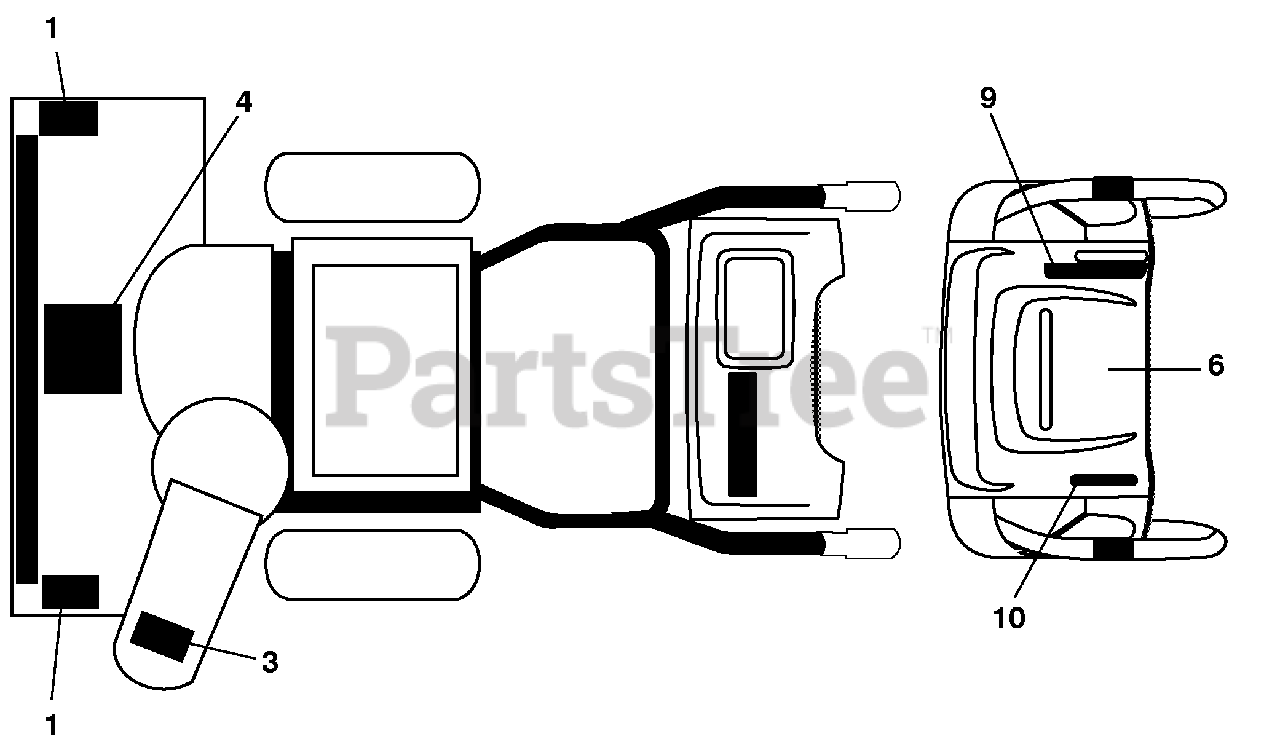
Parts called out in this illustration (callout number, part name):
1	DECAL, DANGER
3	DECAL, DANGER, DEFLECTOR
4	DECAL, DANGER
6	DECAL, INSTRUC.
9	DECAL, CONS RT SPD/LEV/PWRST
10	DECAL, CONS LT DEF/LEV/PWRST
10	OWNER'S MANUAL, ENGLISH
10	OWNER'S MANUAL, FRENCH
